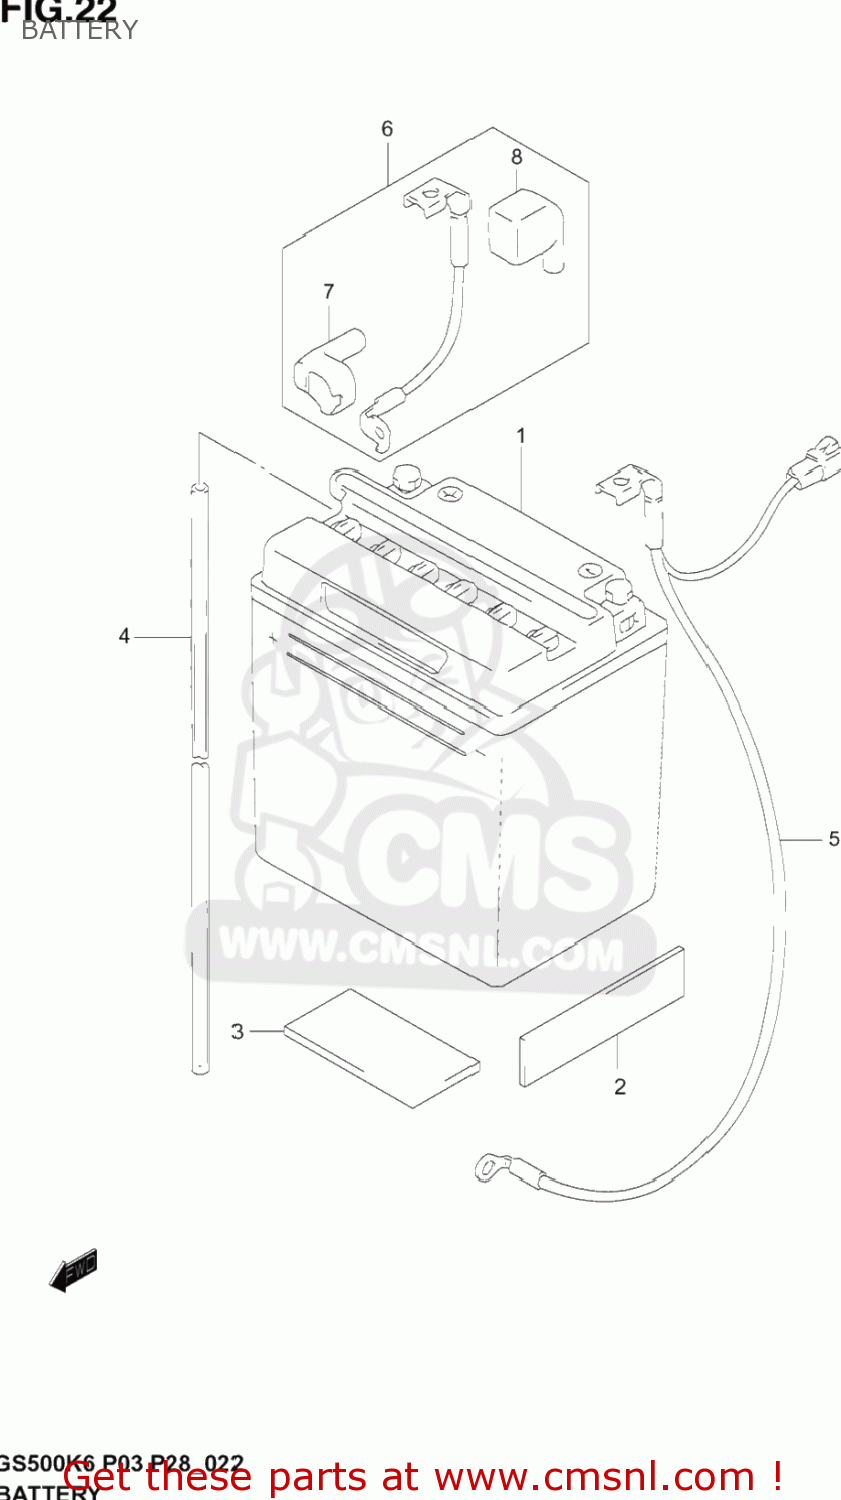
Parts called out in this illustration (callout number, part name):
1	BATTERY (FB10L-B2,12V11AH)
2	PROTECTOR (20X90X3)
3	CUSHION (40X75X5)
4	HOSE, EXHAUST
5	WIRE,BATTERY MINUS
6	LEAD WIRE,BATT
7	CAP,STARTER RELAY TERMINAL
8	CAP,BATTERY
